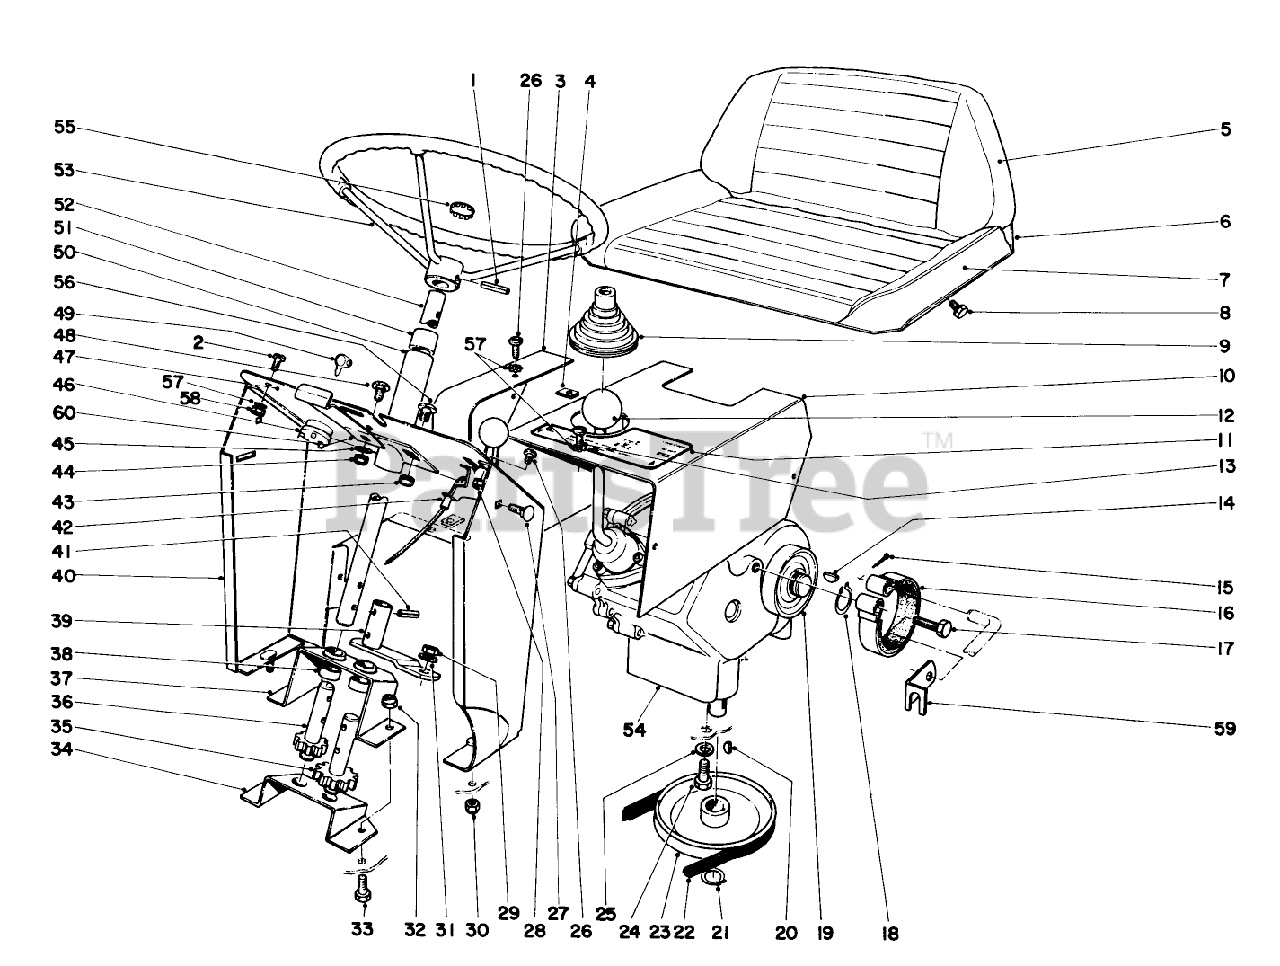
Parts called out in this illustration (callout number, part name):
1	PIN-ROLL
4	NUT-CLIP,U
5	Cushion Back
6	Frame Seat
7	Cushion Seat
10	Cover Transmission
11	Decal Shift Pattern
14	KEY-WOODRUFF
15	PIN-COTTER
18	RING-SNAP
19	Brake Drum
20	KEY-WOODRUFF
21	Retaining Ring
22	TRANS TO ENGINE BELT
23	PULLEY
24	Capscrew
25	WASHER-LOCK/SP
27	SCREW-CARR
28	NUT-KEPS
29	NUT-HEX
31	WASHER-LOCK
33	SCREW-HH
35	Steering Gear
36	Pinion Gear
37	Support Steering
39	Steering Arm
40	Rear Hood Support (Recoil)
41	PIN-ROLL, SLOTTED
42	Throttle Control
44	NUT-LOCK, CONE
45	WASHER-FLAT
47	Decal Control Panel (Recoil)
50	Steering Tube Assy.
52	Shaft Steering
53	Steering Wheel
54	Transmission
56	Truss Head Screw
57	WASHER-LOCK, EXT
58	NUT-KEPS
59	Retainer Brake Rod
60	Hood Latch
